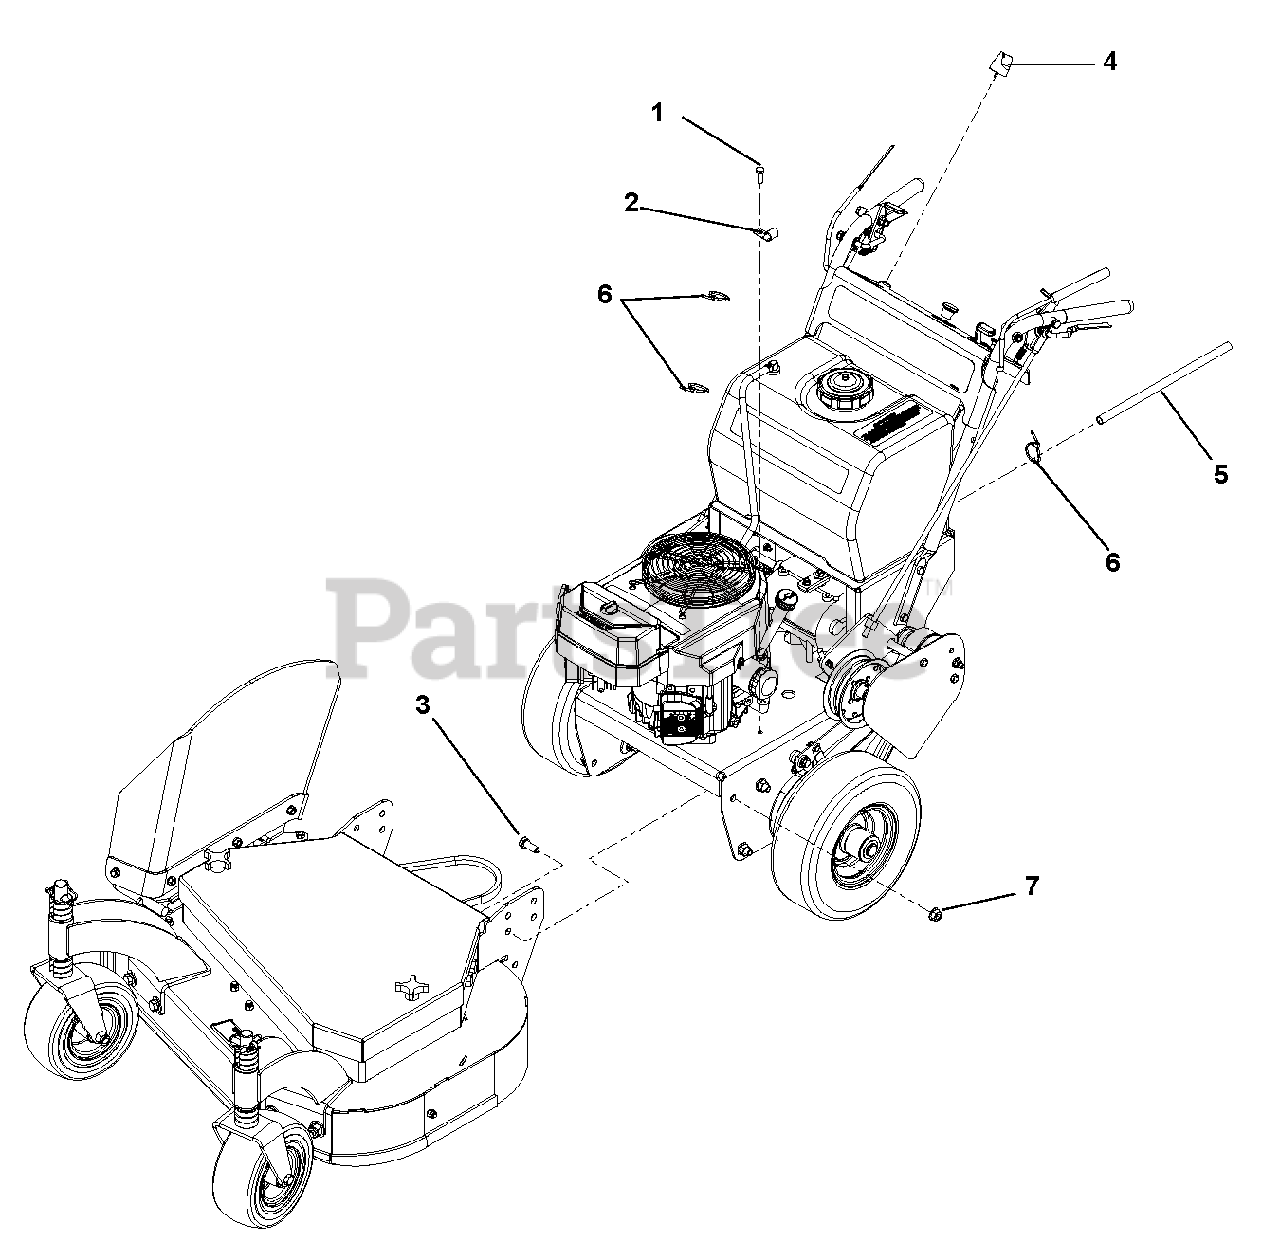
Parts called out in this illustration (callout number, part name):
1	Screw,Tapping .38-16 x .50 Hex Washer Head Thread Rolling
2	Pillow, Clip
3	Bolt, .50-13 x 1.25 Hex 5
4	Key with Shield
5	Tube, Oil Drain 14" Clear Vinyl
6	Cable Tie, .15 x 8.50
7	Nut, .50-13 Nyloc Flange
